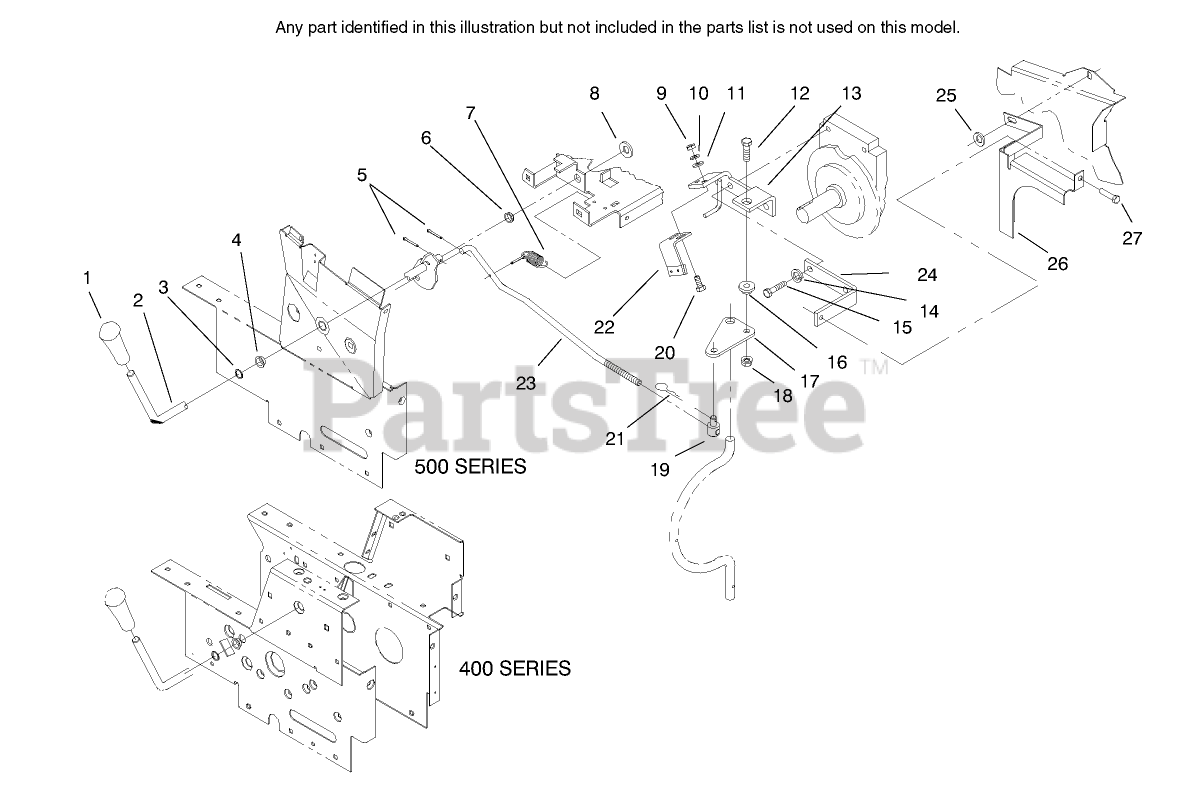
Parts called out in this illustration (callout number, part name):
2	PTO CLUTCH LEVER ASM
3	RING-EXT GRIP
4	BUSHING-NYLINER
5	PIN-COTTER
6	BUSHING-NYLINER
7	SPRING
8	SHIM-WASHER
9	NUT-JAM
10	WASHER-LOCK
11	WASHER-FLAT
13	Bracket-PTO
14	WASHER-LOCK
15	SCREW-HH
16	SPACER-LIFT LINK
17	PLATE
21	PIN-HAIR
22	BRAKE ASM
23	ROD-PTO CLUTCH
24	Bar-Support
25	WASHER-PLAIN
